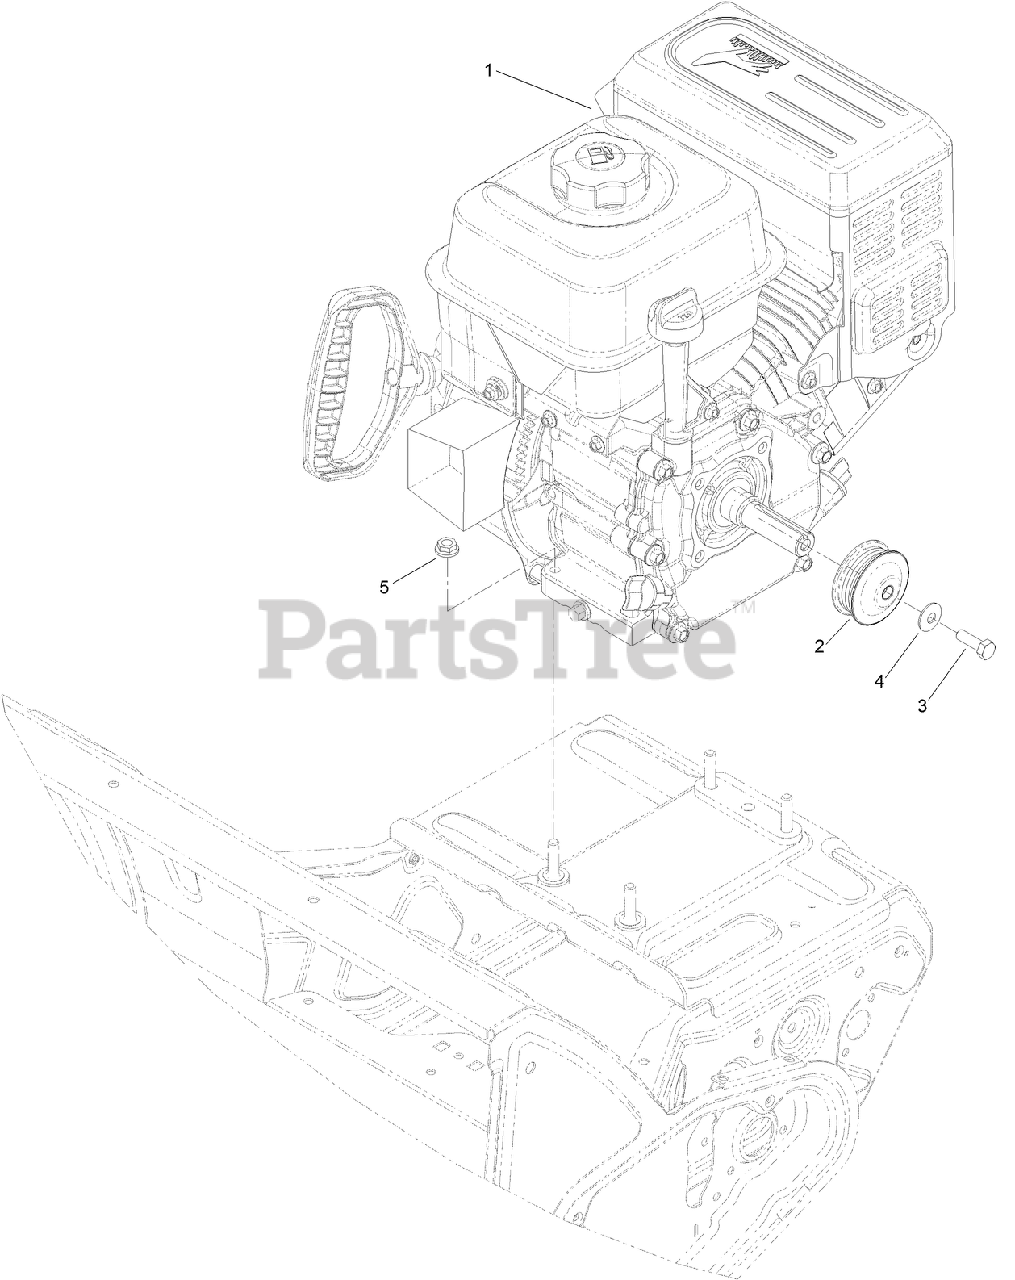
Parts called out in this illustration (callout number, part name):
1	ENGINE-G210FS-2
2	PULLEY-ENGINE
3	SCREW-HH, PATCH
4	WASHER-BELLEVILLE
5	NUT-HF
